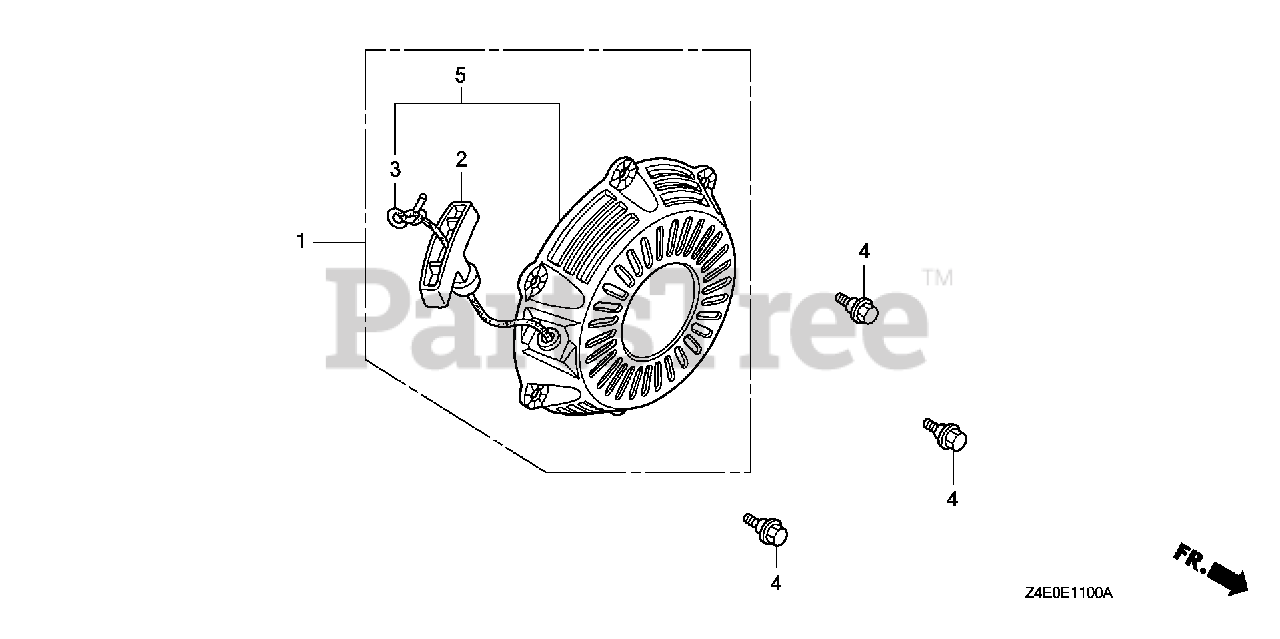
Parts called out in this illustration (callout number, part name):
1	STARTER ASSY. *R280*
1	STARTER ASSY., RECOIL *R280* (POWER RED)
2	GRIP, STARTER
3	ROPE, STARTER
4	BOLT, FLANGE (6MM)
